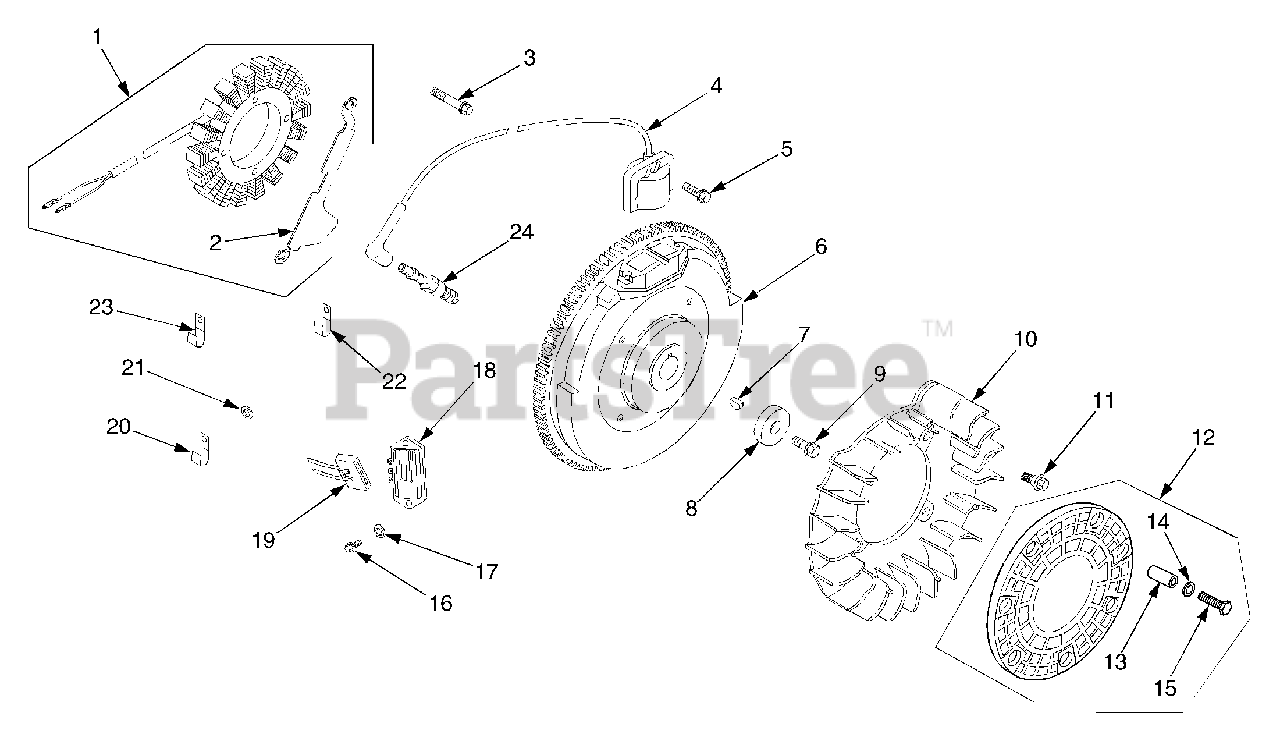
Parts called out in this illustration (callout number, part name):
1	Stator Kit, 15 Amp
2	Bracket, Stator Wire
3	Screw, Stator Mtg. M5 x .8 x 25
4	Module, Ignition
5	Screw, Module M5 x .8 x 20
6	Flywheel Assembly
8	Washer, Flywheel Mtg. Screw
9	Screw, Flywhl Mtg, M10x1.5 x 46
10	Fan
11	Bolt, Shoulder
12	Screen, Grass
14	Washer, Plain
15	Screw, Hex Hd. M4 x 0.7 x 25
16	Screw Phillips Hd., #11-16 x .875
17	Washer, Plain
18	Regulator - Rectifier
19	Connector, Regulator-Rectifier
20	Clip, Cable
21	Washer, Plain 1/4"
23	Clip, Cable
24	Spark Plug
